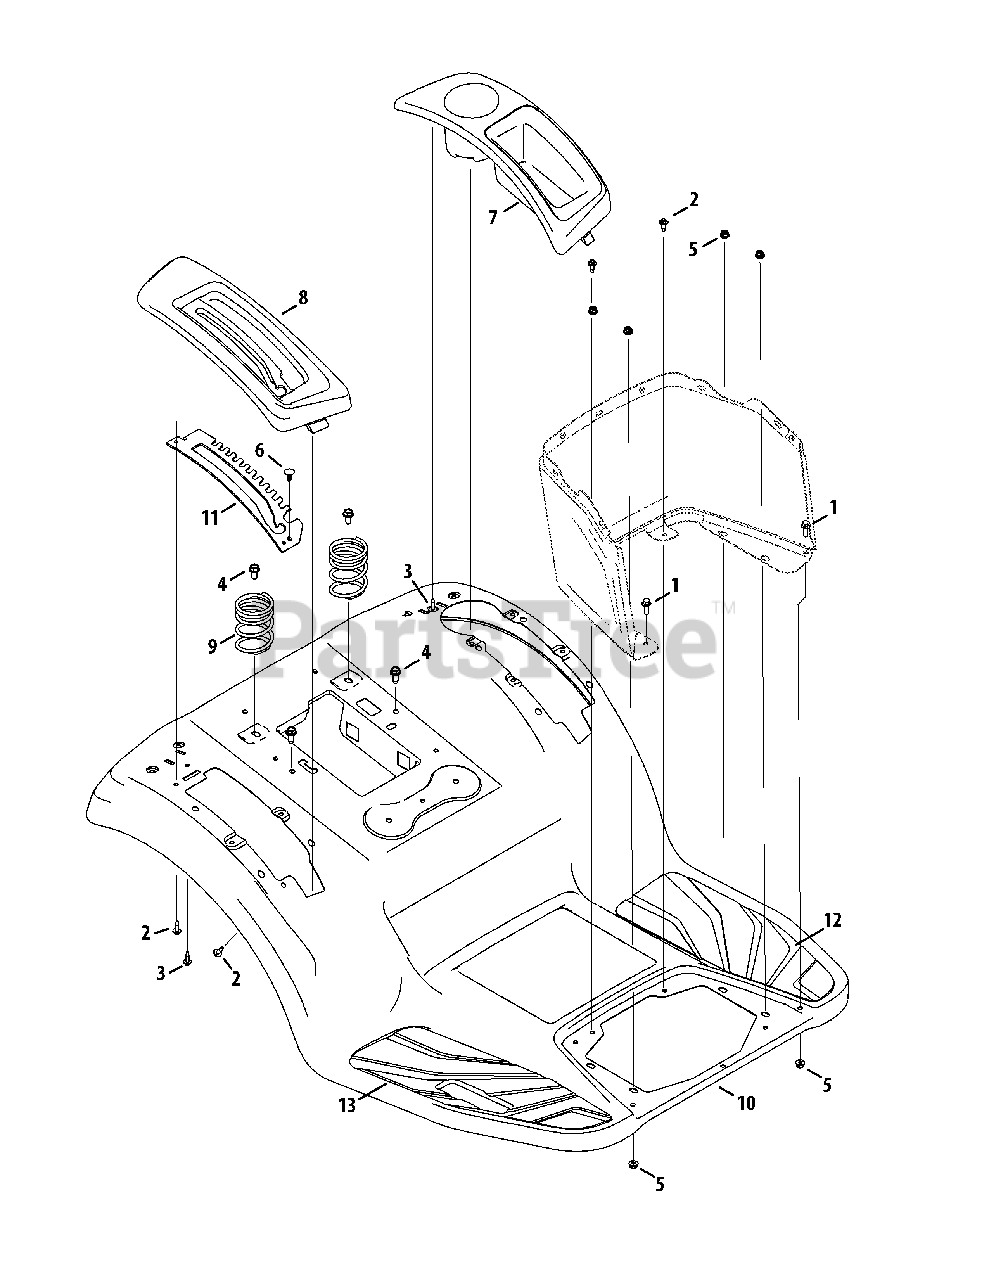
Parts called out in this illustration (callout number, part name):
1	Hex flange Screw, 1/4-20 x .75
2	Screw, M6-1 x .625
3	Screw, 1/4-10 x .75
4	Screw, Self-tapping, 5/16-18, 0.750,
5	Nut, Flange Lock, 1/4-20, Nylon
6	Ratchet Clip, .250 DIA
7	Cover, LH
8	Cover, RH, Electric PTO
9	Compression Spring, 2.50 x 3.951 x .207
10	Fender
12	Pad, Foot, LH
13	Pad, Foot, RH
